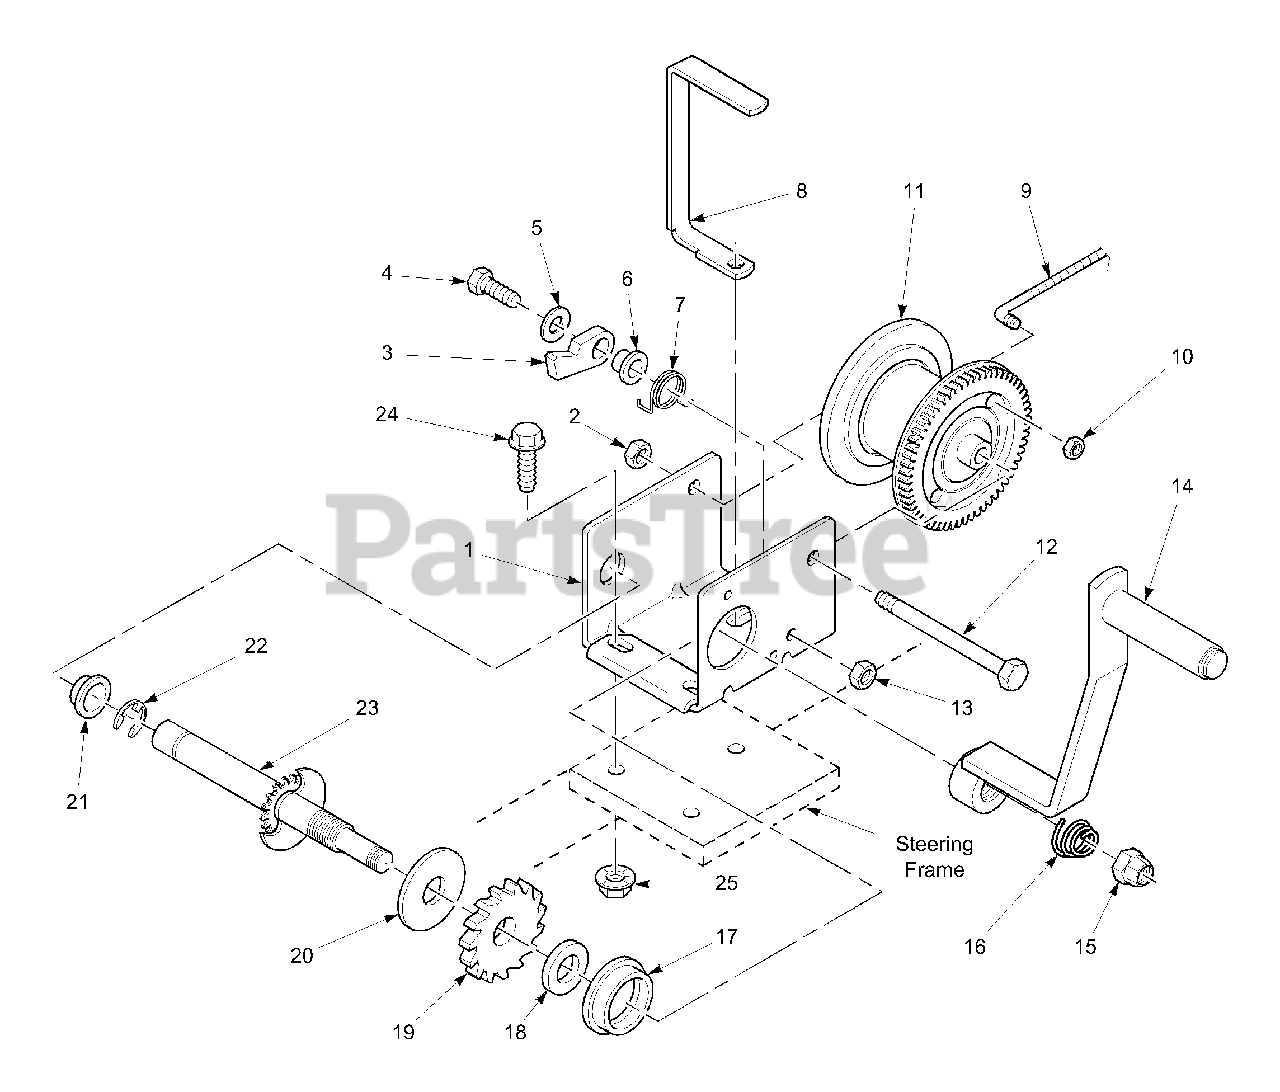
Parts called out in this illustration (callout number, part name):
1	Winch Assembly
2	Locknut, 7/16-14
3	Ratchet Pawl
4	Ratchet Bolt
5	Flatwasher
6	Ratchet Spacer
7	Ratchet Spring
8	Cable Guide
9	Winch Cable Assembly
10	Hex Locknut, 1/4-28
11	Winch Reel
12	Reel Shaft
13	Hex Locknut, 3/8-16
14	Winch Handle
15	Handle Nut
16	Handle Spring
17	Shaft Bushing
18	Pressure Washer
19	Ratchet Wheel
20	Pressure Plate
21	Shaft Bushing
22	E-Ring
23	Drive Shaft
24	Serr. Flg. HH Capscrew, 3/8-16 x 1"
25	Serr. Flg. HH Nut, 3/8-16
